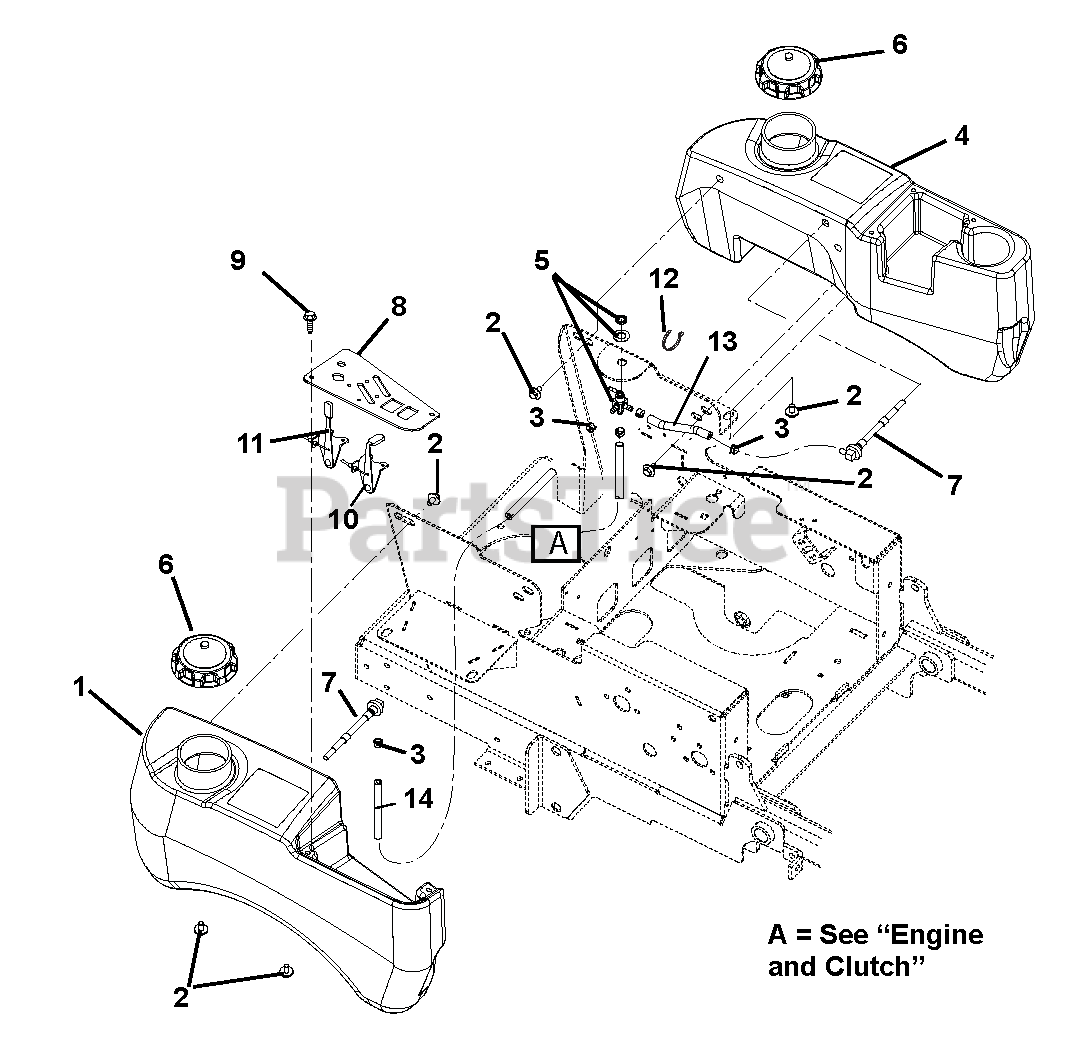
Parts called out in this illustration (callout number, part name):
1	TANK, FUEL RH W/O HOSE
2	BOLT, SEMS .31-18 X .62
3	CLAMP, FUEL LINE
4	TANK, LH FUEL CZ W/O HOSE
4	Tank, Left Hand Fuel 100 S. without Hose (SN 000800 and up)
5	VALVE, FUEL
6	CAP - FUEL
7	KIT,16.5"FUEL LINE CZ(2 HOSES)
8	PANEL, CONTROL
9	SCR-MCH 10-24X.50 HWHSTAINLESS
10	CABLE, THROTTLE OR CHOKE
10	CABLE, THROTTLE
11	CABLE, CHOKE
12	CABLE TIE LG 5-1/2
13	HOSE, .25 LOW-PERM BULK GAS
14	HOSE, .25 LOW-PERM BULK GAS
